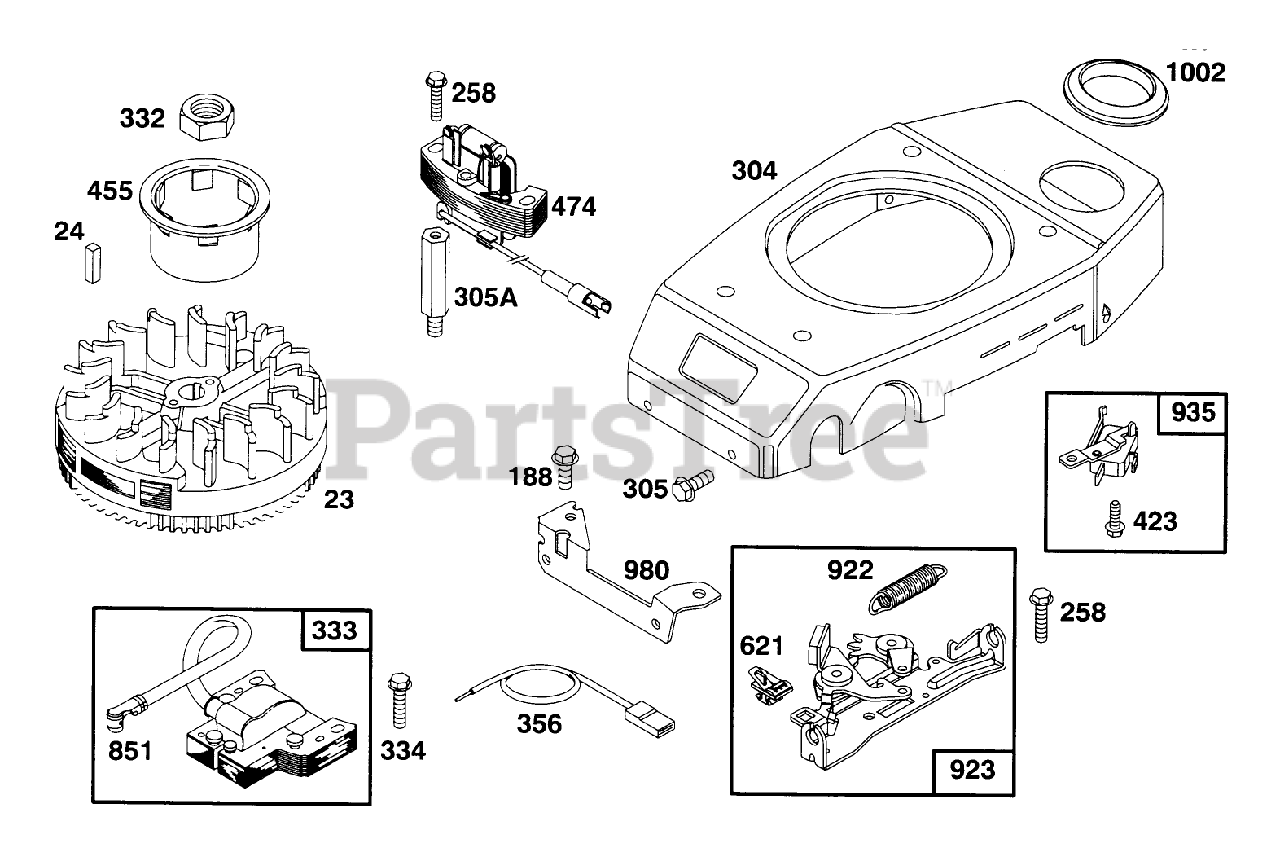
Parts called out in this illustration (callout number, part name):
23	FLYWHEEL - MAGNETO
24	KEY - FLYWHEEL
305	SCREW - HEX HEAD
332	NUT - HEXAGON
334	SCREW - SEM
356	WIRE - GROUND
621	STOP SWITCH
980	BRACKET-BLOWER HSG
